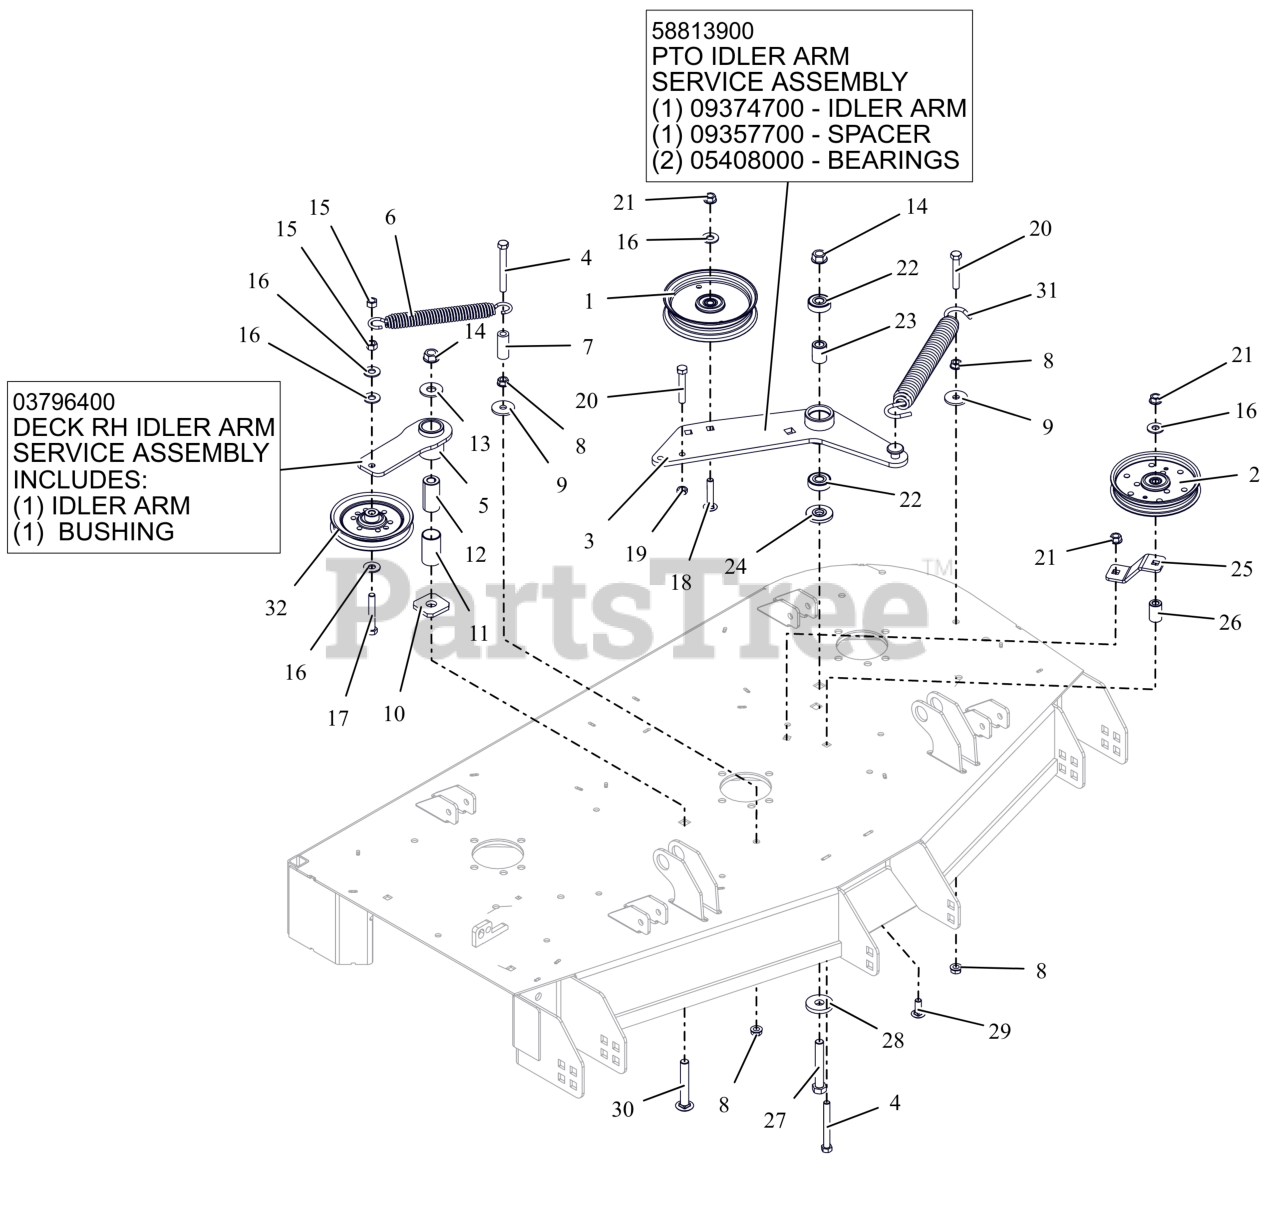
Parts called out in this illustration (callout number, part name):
1	IDLER- FLAT - 5.00" X .75"
2	IDLER- 5" FLANGED
3	WLDMT, IDLER ARM PT660
3	PTO IDLER ARM
3	SPACER .510 X .867 X 1.1485
3	BRG-BALL .500X1.38X.437
4	BLT, HEX .38-16X3.25 G5 ZCC
5	WMT, IDLER ARM - BLACK
5	ASM, IDLER ARM (DECK)
6	SPRING- EXTENSION
7	HOSE, .38 X 1.65
8	NUT, SPNLK-FLG .38-16 G5 ZCC
9	WSHR,FLT .406X1.375X.135 ZCC
10	WSHR-FLT .640X1.75X.250
11	BSHG, 1.00X1.125X1.937
12	BSHG, SPCR .502X.997X2.03 PM
13	WSHR,FLT .563X1.375X.109 ZCC
14	NUT-LK-CTR-FLG .500-13 GG ZCC
15	NUT-LK-CTR .38-16 ZC120
16	WSHR,FLT .438X1.00X.083 ZCC
17	BLT, HEX .38-16X2.50 G5 ZCC
18	BLT,RHSSN.375-16X2.00 G5 ZCC
19	NUT-JAM .375-16 G2 ZCC
20	BLT,HEX .38-16X2.25 G5 ZCC
21	NUT-LK-CTR-FLG .375-16 GF ZCC
22	BRG-BALL .500X1.38X.437
23	SPACER .510 X .867 X 1.1485
24	SPACER, IDLER ARM
25	PTO FIXED IDLER MTG BRKT-ORG
26	BUSHING, SLV .380X.750X1.190
27	BLT,HEX .50-13X3.25 G5 ZCC
28	WSHR-FL-STL 0.557X1.625X0.25 ZCC
29	BLT,RHSSN .38-16X1.00 G5 ZCC
30	BTL,RHSSN .500-13 X 3.25 G5 ZCC
31	SPRING, EXTENSION
32	IDLER, V, 5.00X.38
